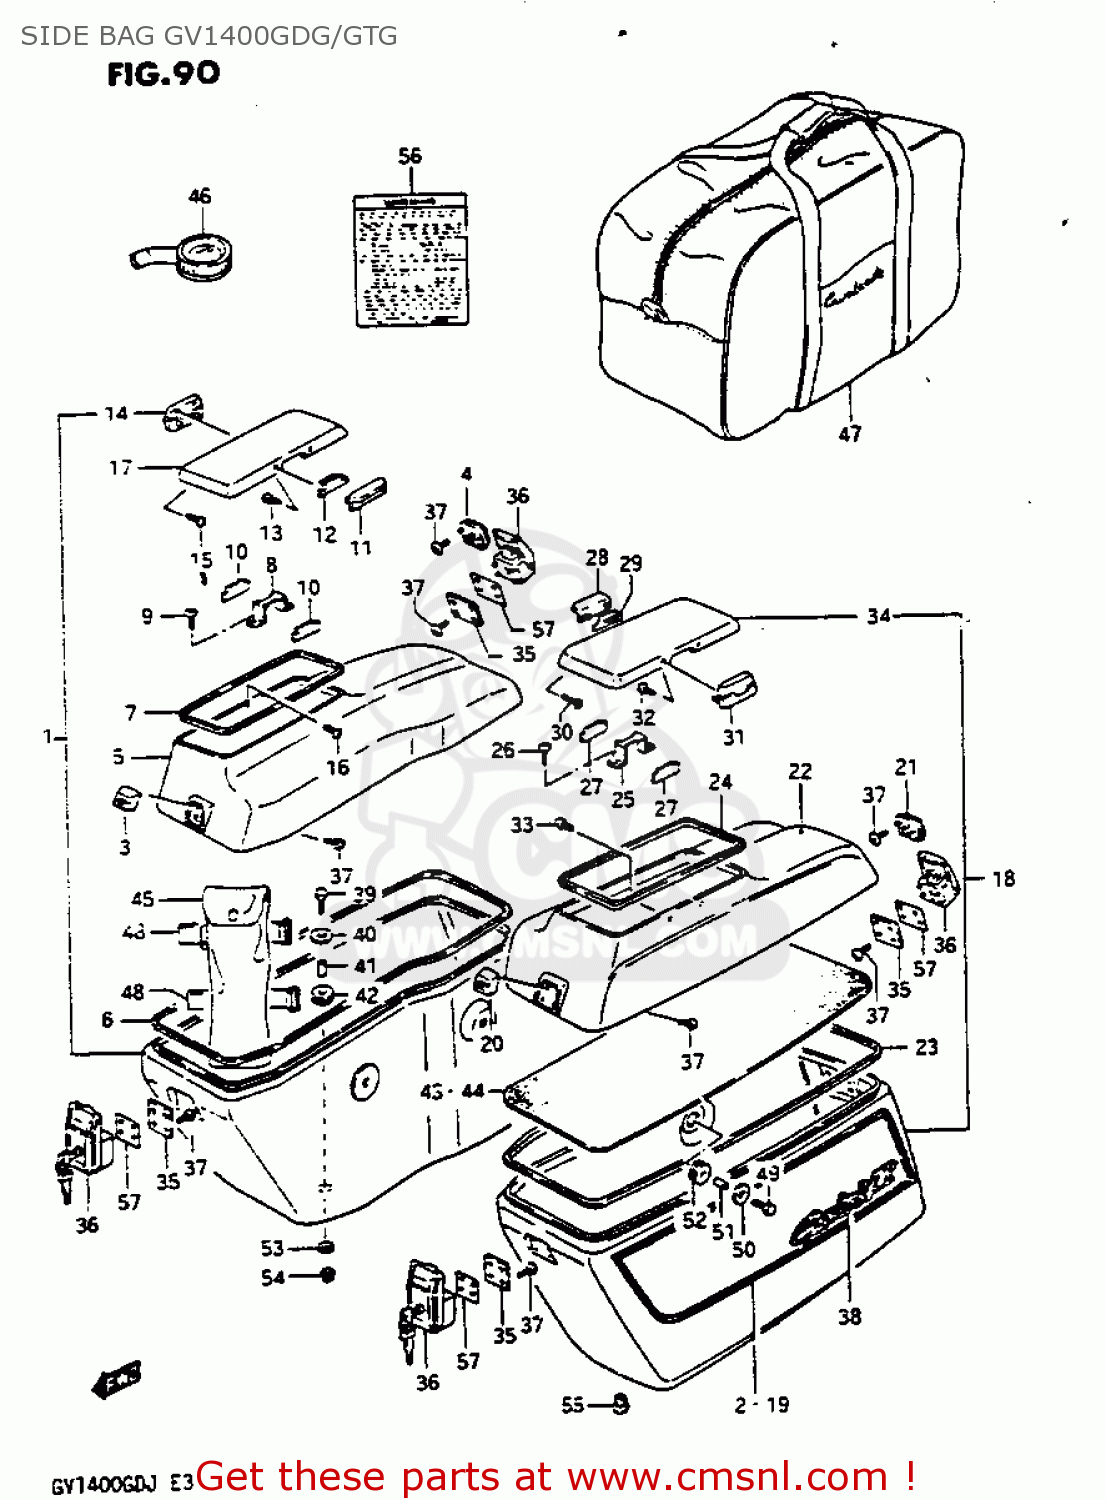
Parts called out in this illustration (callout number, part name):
1	SIDE BAG ASSEMBLY,RIGHT
2	TAPE SET,SIDE BAG,RIGHT
3	PLATE,TRUNK LID LOCK
4	PLATE,SIDE BAG LID LOCK
5	LID,SIDE BAG,RIGHT
6	SEAL,SIDE BAG
7	SEAL,SIDE BAG
8	HOLDER,LID LOCK MAGNET
9	SCREW
10	PLATE,LID LOCK
11	LEVER,SIDE POCKET OPEN
12	PLATE,LID LOCK NO.1
13	SCREW
14	HINGE,LID SIDE BAG POCKET
15	SCREW
16	SCREW
17	LID,SIDE BAG POCKET
18	SIDE BAG ASSEMBLY,LEFT
19	TAPE SET,SIDE BAG,LEFT
20	PLATE,TRUNK LID LOCK
21	PLATE,SIDE BAG LID LOCK
22	LID,SIDE BAG,LEFT
23	SEAL,SIDE BAG
24	SEAL,SIDE BAG
25	HOLDER,LID LOCK MAGNET
26	SCREW
27	PLATE,LID LOCK
28	LEVER,SIDE POCKET OPEN
29	PLATE,LID LOCK NO.1
30	SCREW
31	HINGE,LID SIDE BAG POCKET
32	SCREW
33	SCREW
34	LID,SIDE BAG POCKET
35	SET PLATE,LOCK SIDE BA
36	LOCK SET,SIDE BAG
37	SCREW
38	EMBLEM,SIDE BAG,LEFT
39	BOLT
40	WASHER (6.5X29X1.6)
41	SPACER(6.3X9.3X16.5)
42	CUSHION
43	SEAT, BOTTOM RH
44	SEAT, BOTTOM LH
45	TOOL ASSY
46	GAUGE ASSY,AIR PRESSURE
47	LUGGAGE BAG,SIDE BAG
48	BAND
49	BOLT
50	WASHER (6.5X29X1.6)
51	SPACER(6.3X9.3X16.5)
52	CUSHION
53	WASHER (6.5X18X2)
54	NUT
55	CAP(OD:12)
56	LABEL (WARNING)
57	PACKING SEAT
